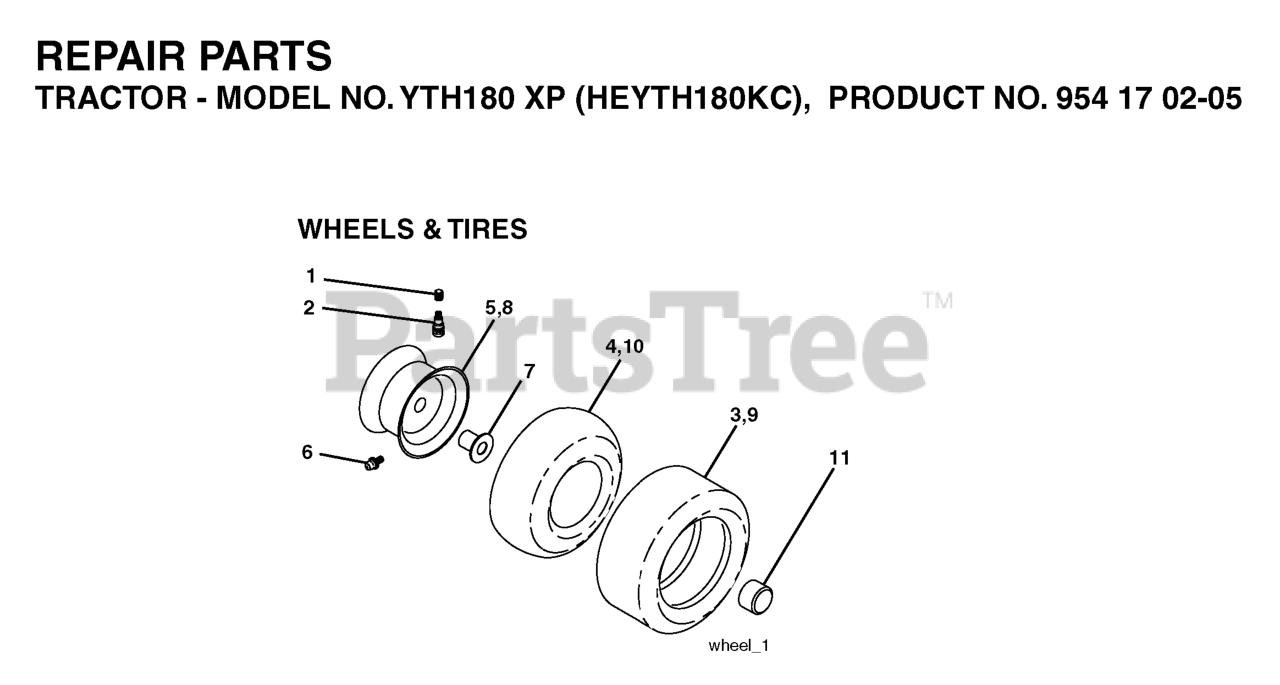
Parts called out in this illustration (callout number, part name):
2	VALVE STEM LT
3	TIRE HEAVY DUTY
4	TUBE.5.3/4.5/6
5	RIM ASM 6" FRONT SILVER
6	FITTING LT
7	BEARING T
8	RIM ASM 8" REAR SILVER
9	TIRE.TS.20X10-8
10	TUBE
11	CAP, AXLE BLK
